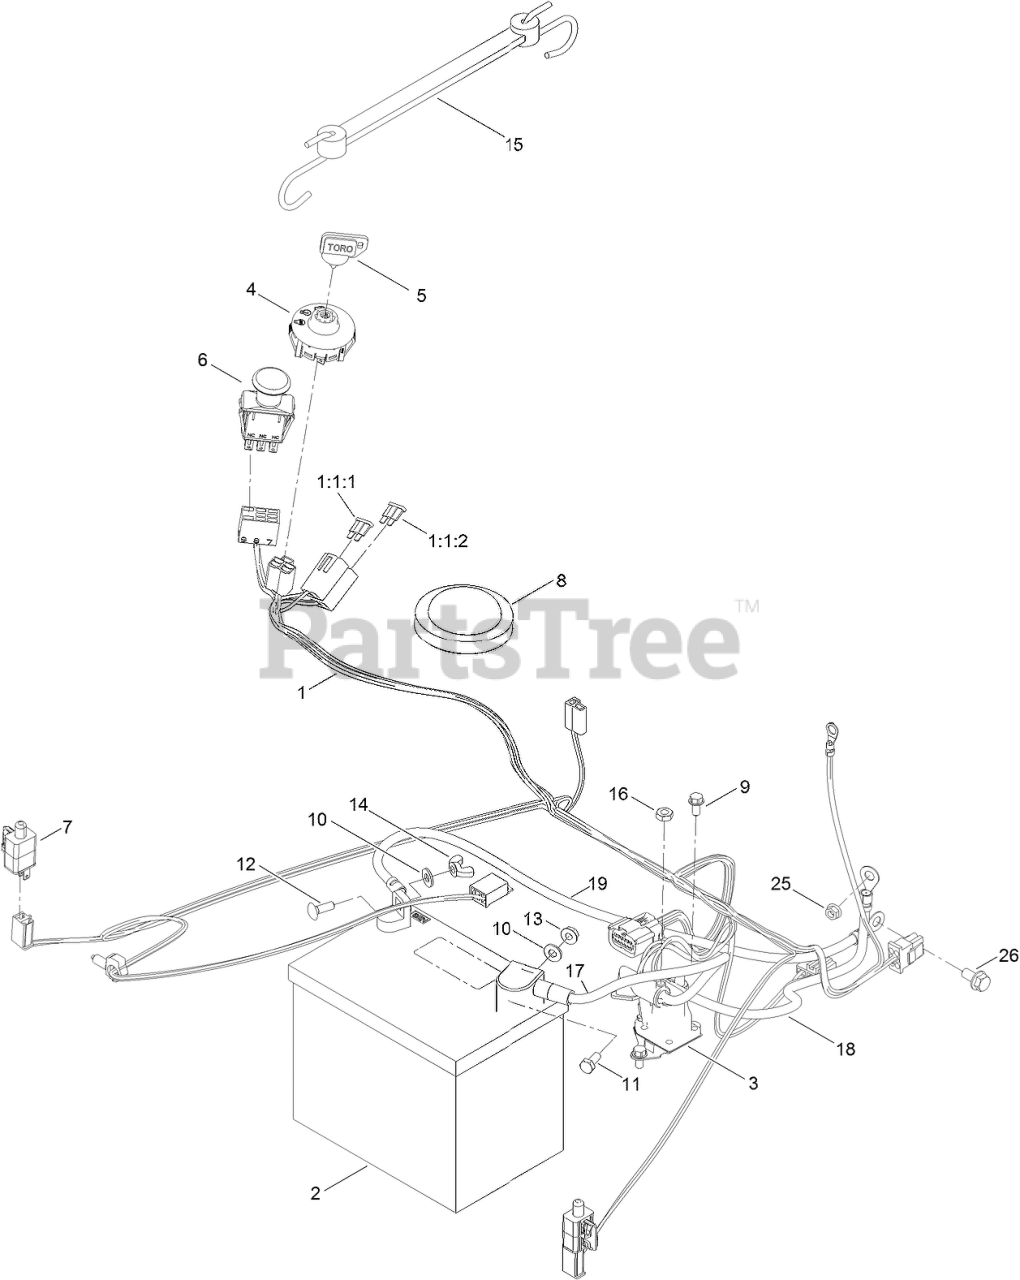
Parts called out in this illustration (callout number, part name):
1	HARNESS-WIRE
1:1:1	FUSE-BLADE, 30 AMP
1:1:2	FUSE-BLADE, 25 AMP
2	BATTERY
3	SOLENOID
4	SWITCH-IGNITION
5	KEY-IGNITION
6	SWITCH-PTO
7	SWITCH
8	SWITCH-SEAT
9	SCREW-HWH
10	WASHER-FLAT
11	SCREW-HH
12	BOLT-CARR
13	NUT-HF
14	NUT-WING
15	HOLDDOWN-BATTERY
16	NUT-HJ
17	CABLE-BATTERY, RED
18	CABLE-BATTERY, POSITIVE
19	CABLE-BATTERY, BLACK
25	NUT-HF
26	SCREW-HHF
